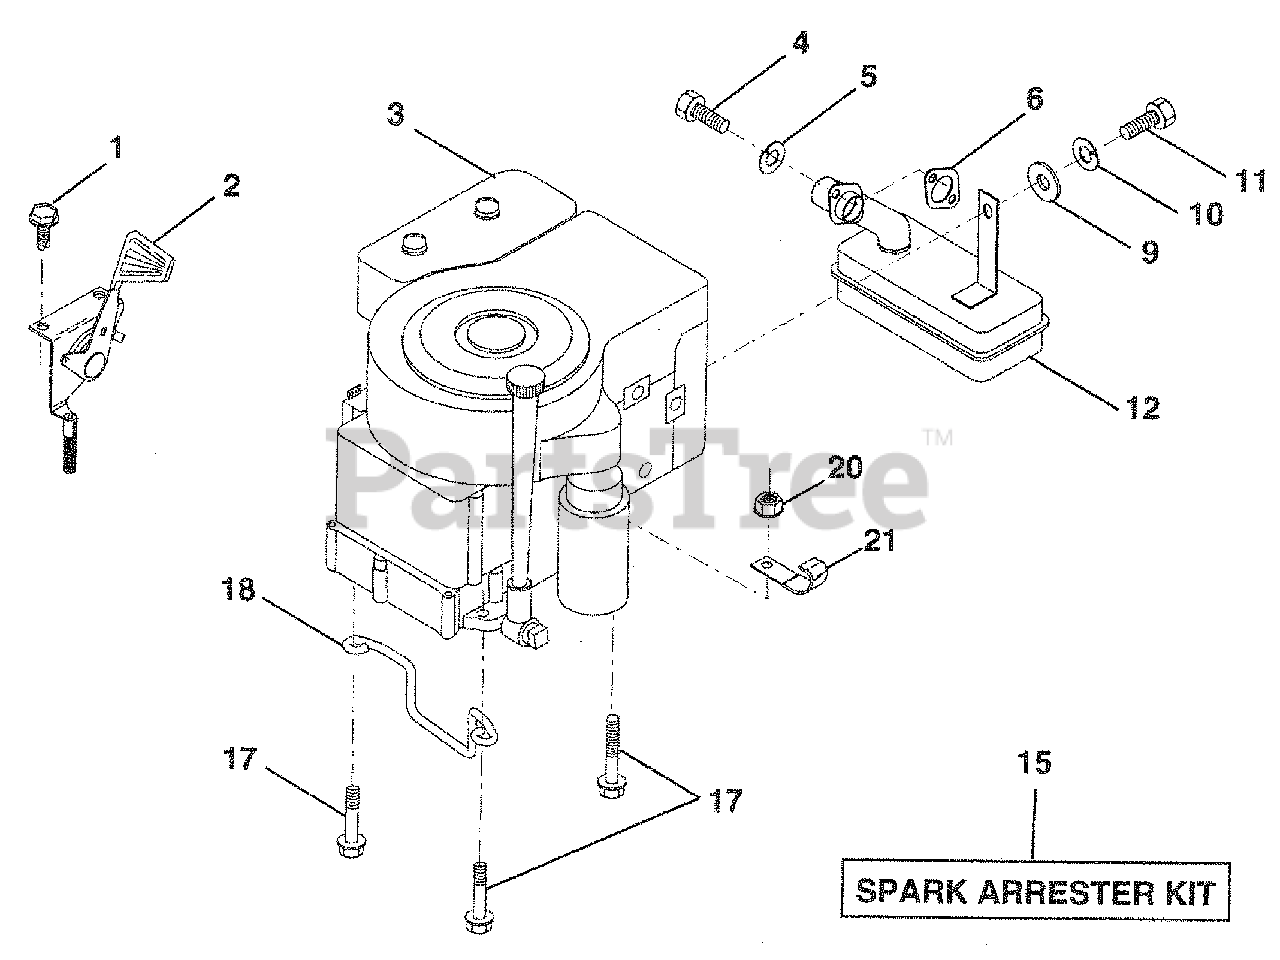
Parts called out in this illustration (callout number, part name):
1	Screw, Tapping 1/4-20 x 1/2
2	Control, Throttle
4	Screw, Hex, Cap 5/16-18 x 3/4
5	Washer, Lock Heavy Helical Spring 5/16
6	Gasket, Exhaust
9	Washer 5/16 x 3/4 x 16
10	Washer, Lock Heavy Hlcl Sprg 1/4
11	Bolt
15	Arrester, Spark
17	Screw, Hex Washer Head, Thdrol. 3/8-16 x 1-1/2
18	Keeper, Ground Drive Belt
20	Nut, Keps 3/8-16
21	Clip, Fuel Line
